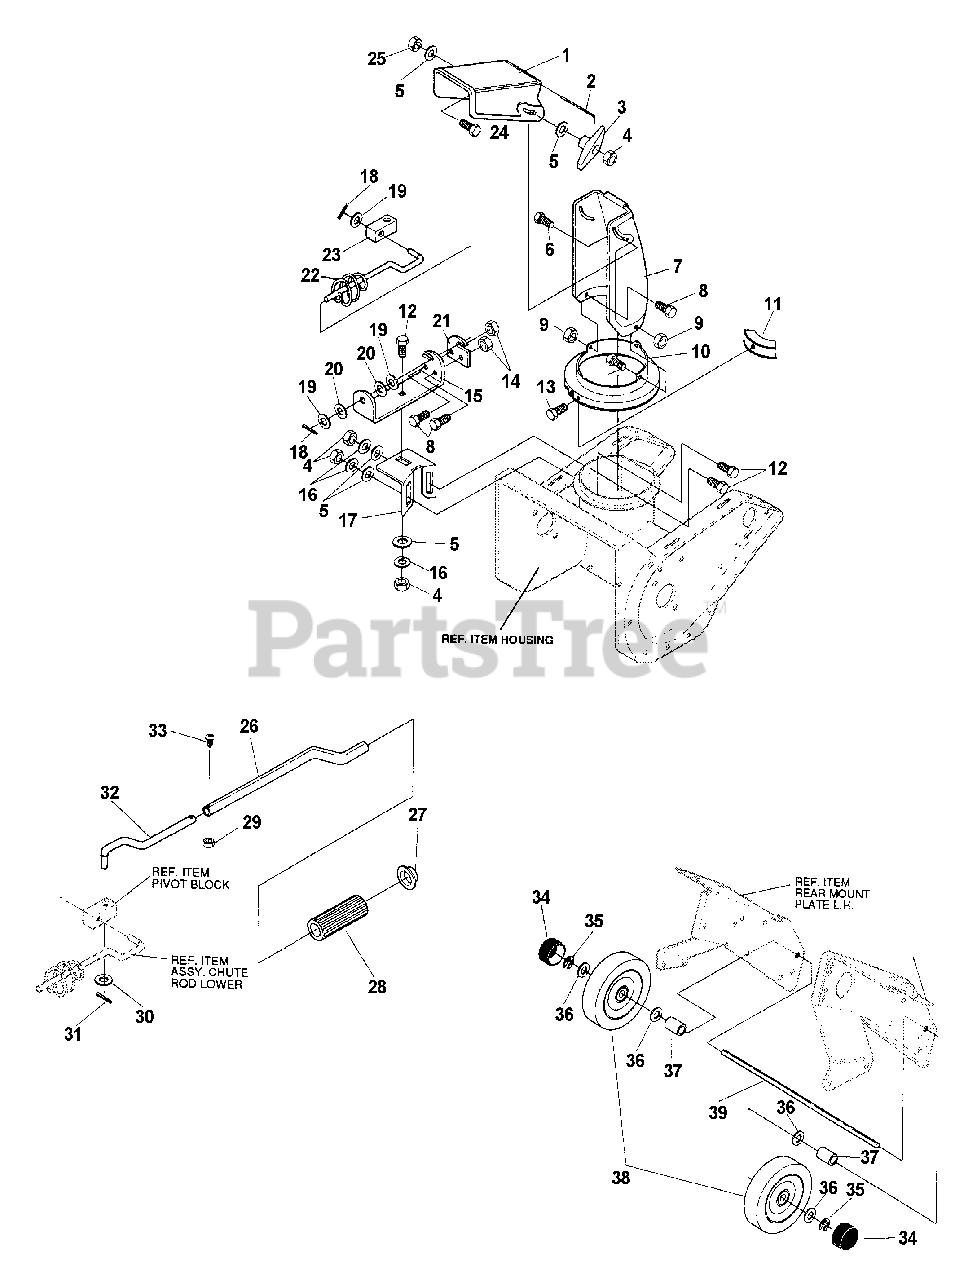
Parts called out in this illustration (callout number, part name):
1	CHUTE, UPR SRS W/OHKLE
2	WIRE, HINGE 6.65 LONG SR
3	KNOB, T 2 BLADE W/5/16-18 NUT
5	WASHER
6	BOLT 5/16"-18×1.25" CARRLN
7	CHUTE, LWR
8	SCREW 1/4"-20×0.50
9	NUT, 1/4"-20
10	RING, LOWER CHUTE
11	CLIP, CHUTE RING PLASTIC
12	BOLT, CARRIAGE 5/16-18×0.75
13	SCREW 1/4"-14×0.63
14	NUT, 1/4"-20
15	BRACKET, CHUTE ROD
16	WASHER
17	BRACKET, WORM ADJUST
18	PIN - COTTER
19	WASHER - 0.40×0.75×0.025"
20	WASHER, SADDLE
21	PLATE, CHUTE ROD
22	ROD ASSY, CHUTE CONTROL LOWER
23	BLOCK, PIVOT PLASTIC
24	SCREW 5/16"-18
25	NUT, 5/16"-18
26	ROD, UPPER CHUTE CONTROL
27	NUT, PUSH, FITS 3/8 DIA
29	NUT
30	WASHER - 0.40×0.75×0.025"
31	PIN - COTTER
32	ROD, CHUTE CONTROL MIDDLE
33	SCREW 010-32×0.88
34	HUB CAP 3/20
35	E-RING
36	WASHER
37	SPACER
38	WHEEL ASSY
39	SHAFT, AXLE 5/21
